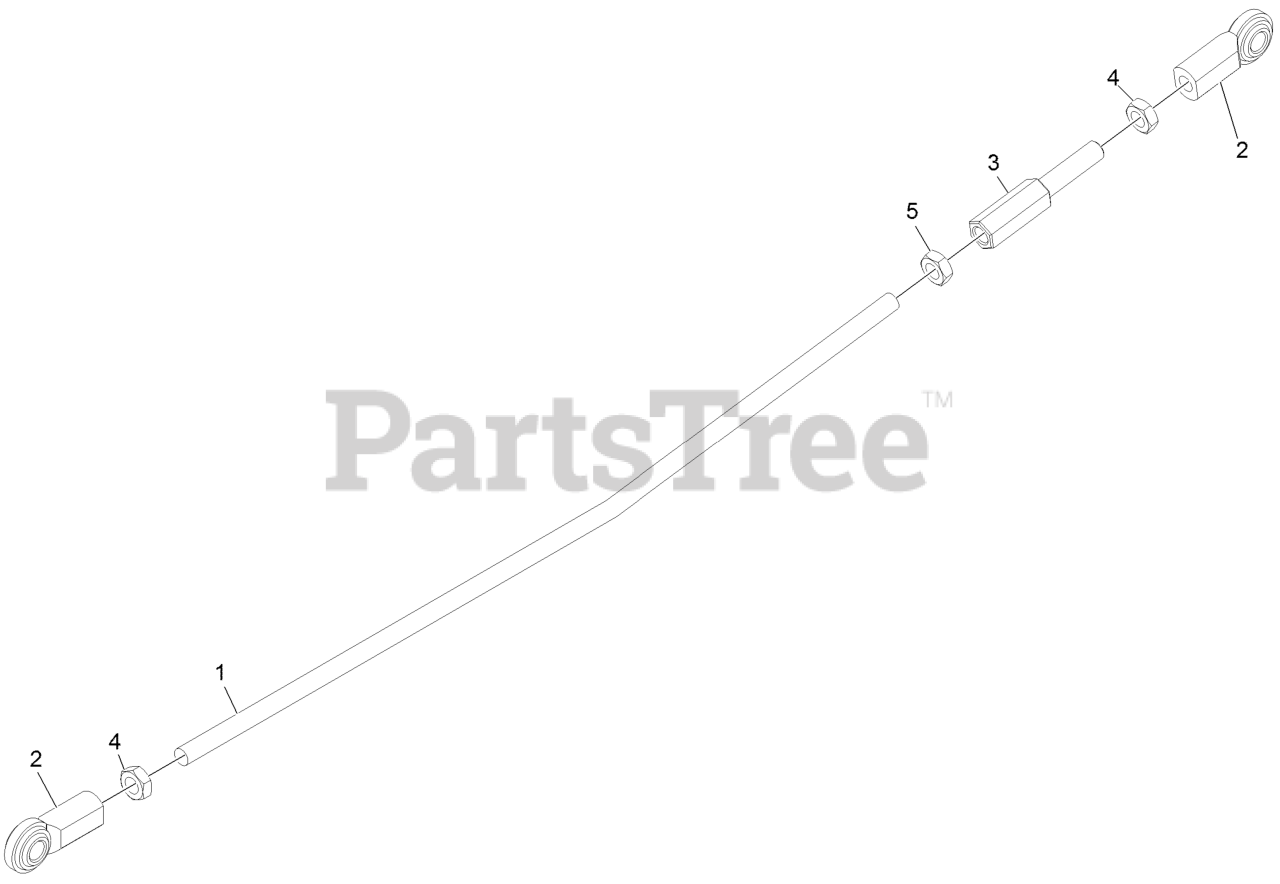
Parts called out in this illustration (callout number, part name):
1	LINK-LOWER, MOTION CONTRO
2	JOINT-BALL, END
3	ROD-ADJUSTMENT
4	NUT-HJ
5	NUT-HEX JAM, LH
